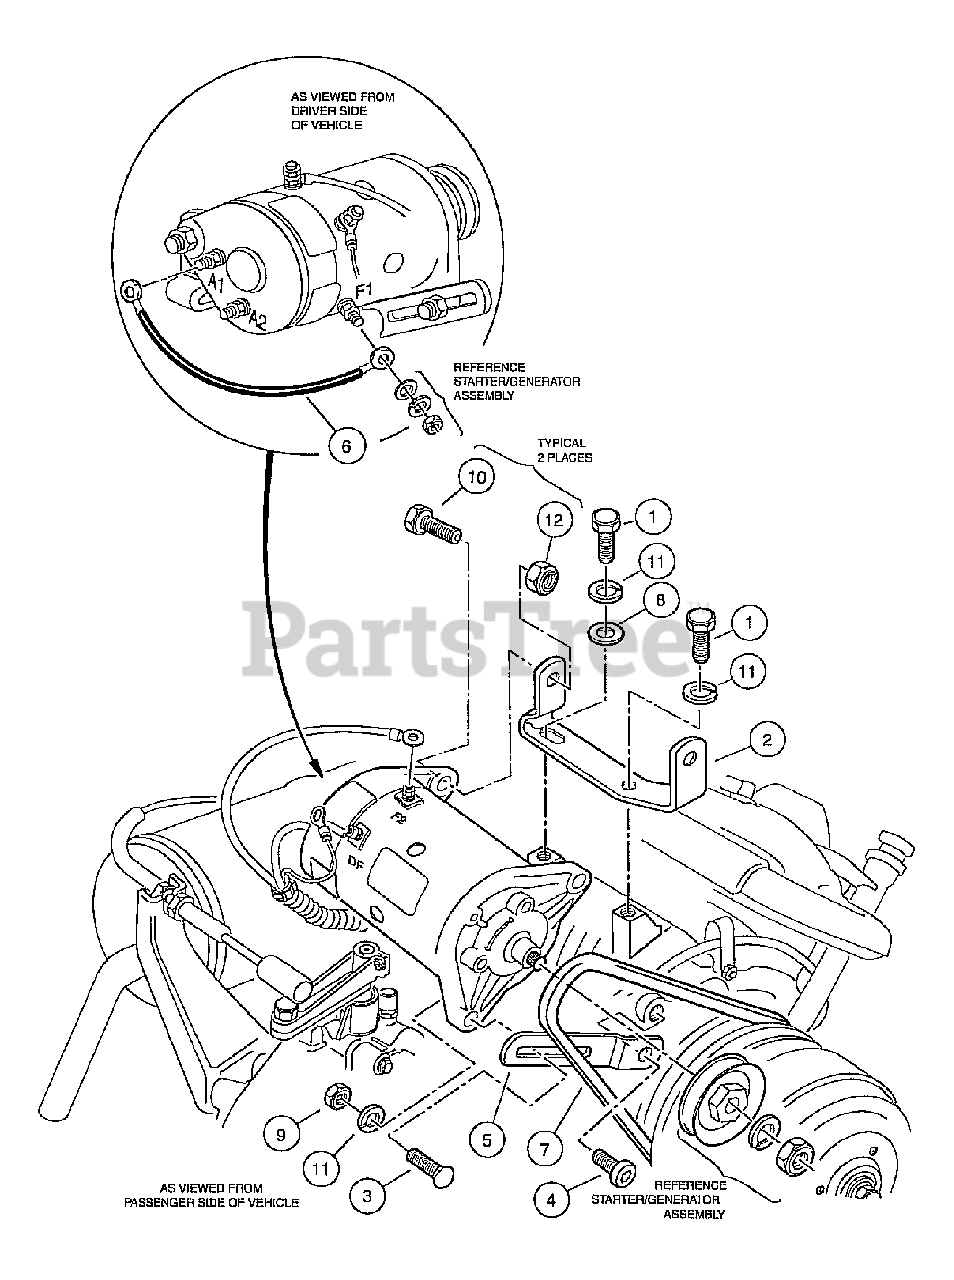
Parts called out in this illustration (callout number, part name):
1	Screw, M8-125 X 22 Hex Gr.8.8
2	Bracket, Starter/Generator Mounting
3	Bolt, Carriage, 5/16-18
4	Screw, MB-1.25 X 18mm Torx
5	Bracket, Starter/Generator Adjustment
6	Wire Assy, #6 Green
8	Washer, 5/16 Type A Flat
9	Nut, 5/16-18 Hex
10	Bolt, 3/8-16 X 1.25 Hex Head
11	Lockwasher, 5/16 Split
12	Locknut, 3/8-16 Hex
